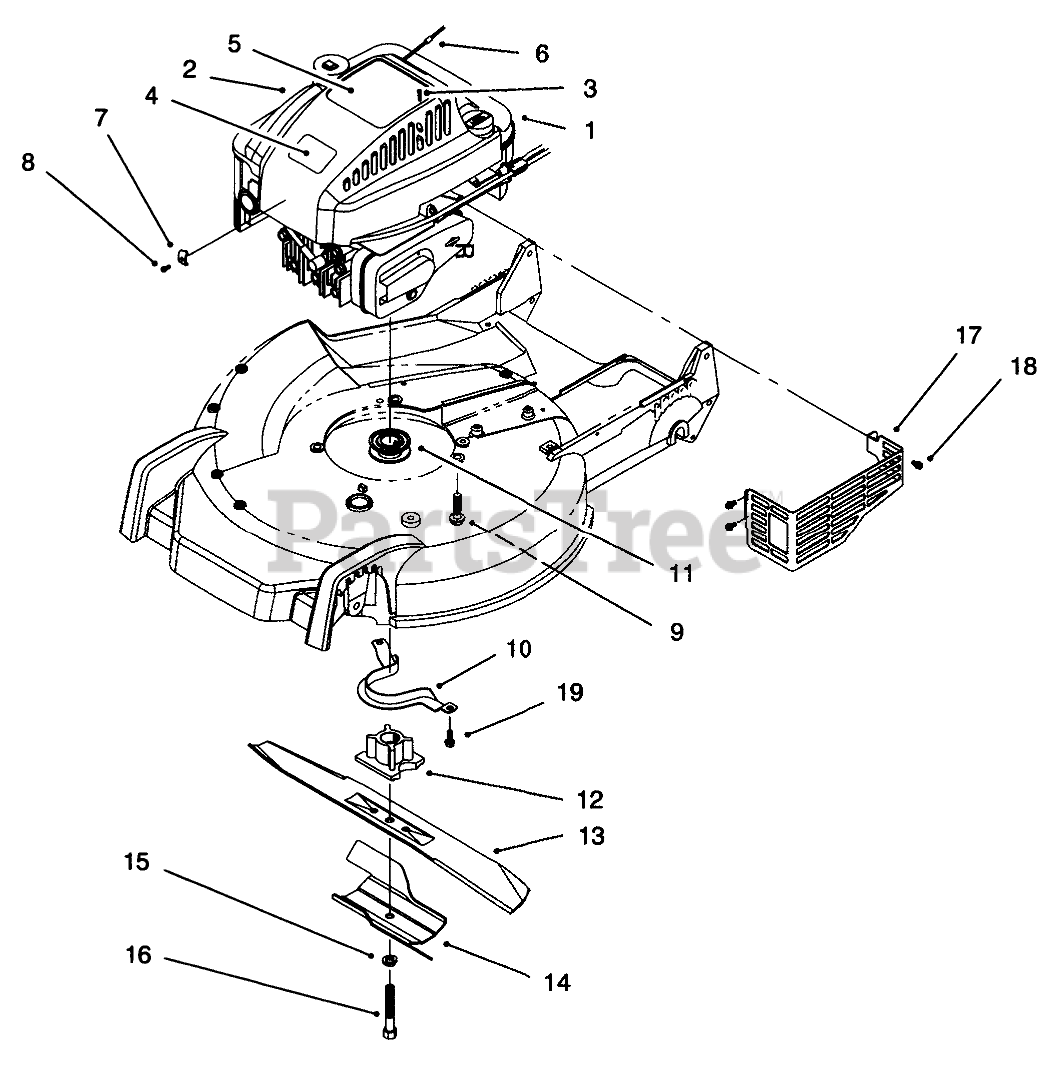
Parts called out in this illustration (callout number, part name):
1	Engine ASM
2	SHROUD-ENGINE
3	SCREW-PPH
4	PLATE-LOGO
5	DECAL - RECOIL
6	STOP-ROPE
7	CLAMP-CASING
8	SCREW-CLAMP
9	SCREW-HWH
10	Guide-Belt
11	PULLEY-DRIVE, ZONE START
12	RETAINER - BLADE
13	Blade
14	Stiffener-Blade
15	WASHER-LOCK
16	SCREW-BLADE
17	SHIELD-MUFFLER
18	SCREW-HWH
19	SCREW-HWHTF
